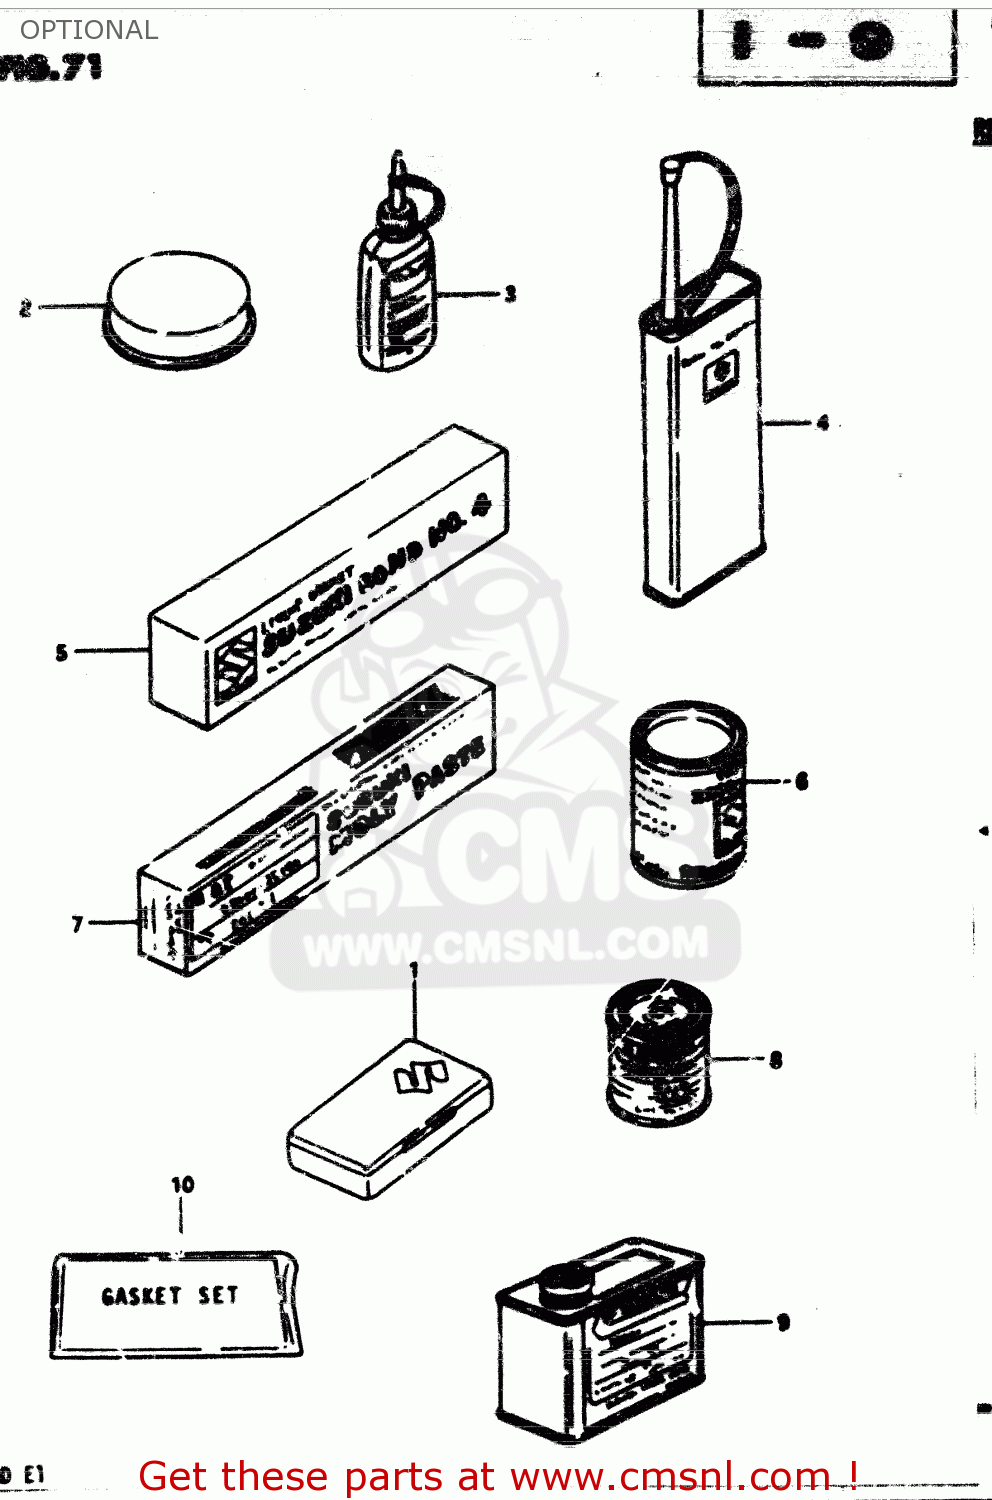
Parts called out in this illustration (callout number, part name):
1	TUBE REPARING TOOL
2	GREASE,PBC FOR BRK PAD 20G
3	** SUPERSEEDED
4	THREAD LOCK NO.1401 CLEAR 200G
5	BOND 1104
6	GREASE(C)EP2 LITHIUM 150G
7	SUZUKI MOLY PASTE
8	PAINT,BLACK
9	PAINT (BLACK)
10	GASKET SET
